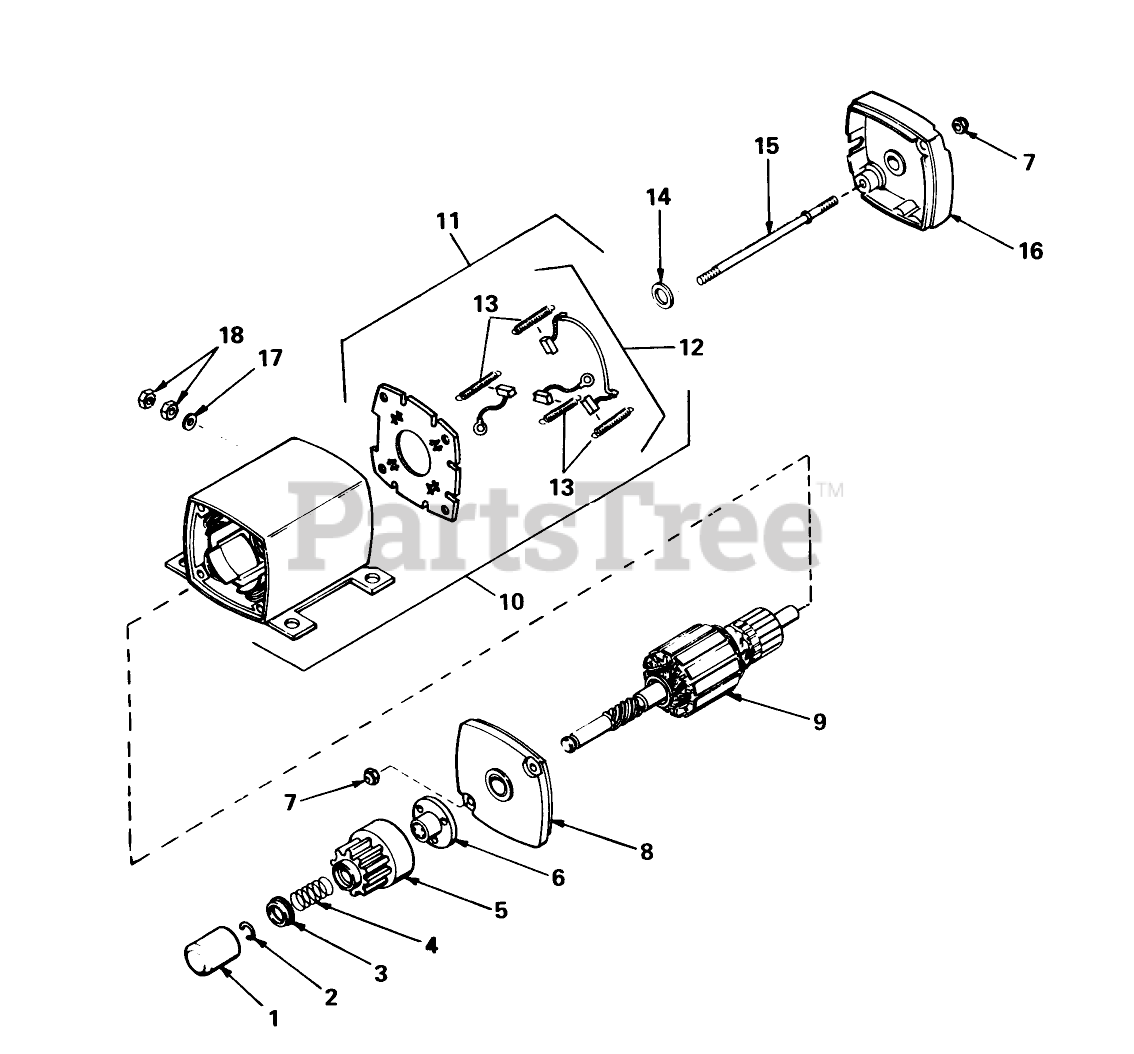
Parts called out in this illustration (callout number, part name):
1	Cover-Dust
2	Ring, Retainer
3	Retainer-Spring
4	Spring-Anti Drift
5	Gear
6	Nut-Engaging
7	Nut-Lock
8	Cap Assy., Drive End
9	Armature
10	Housing Assembly (Incl. Ref. #11)
11	Card Assy., Brush (Incl. No. 12)
12	Brush Spring Kit (Incl. 4 pcs. of #13)
13	1545D SUP TO W/3256
14	Washer-Thrust
15	Bolt
16	2035A67 WIZARD W/34
17	Washer
18	61710/VAR.HILLER AT
